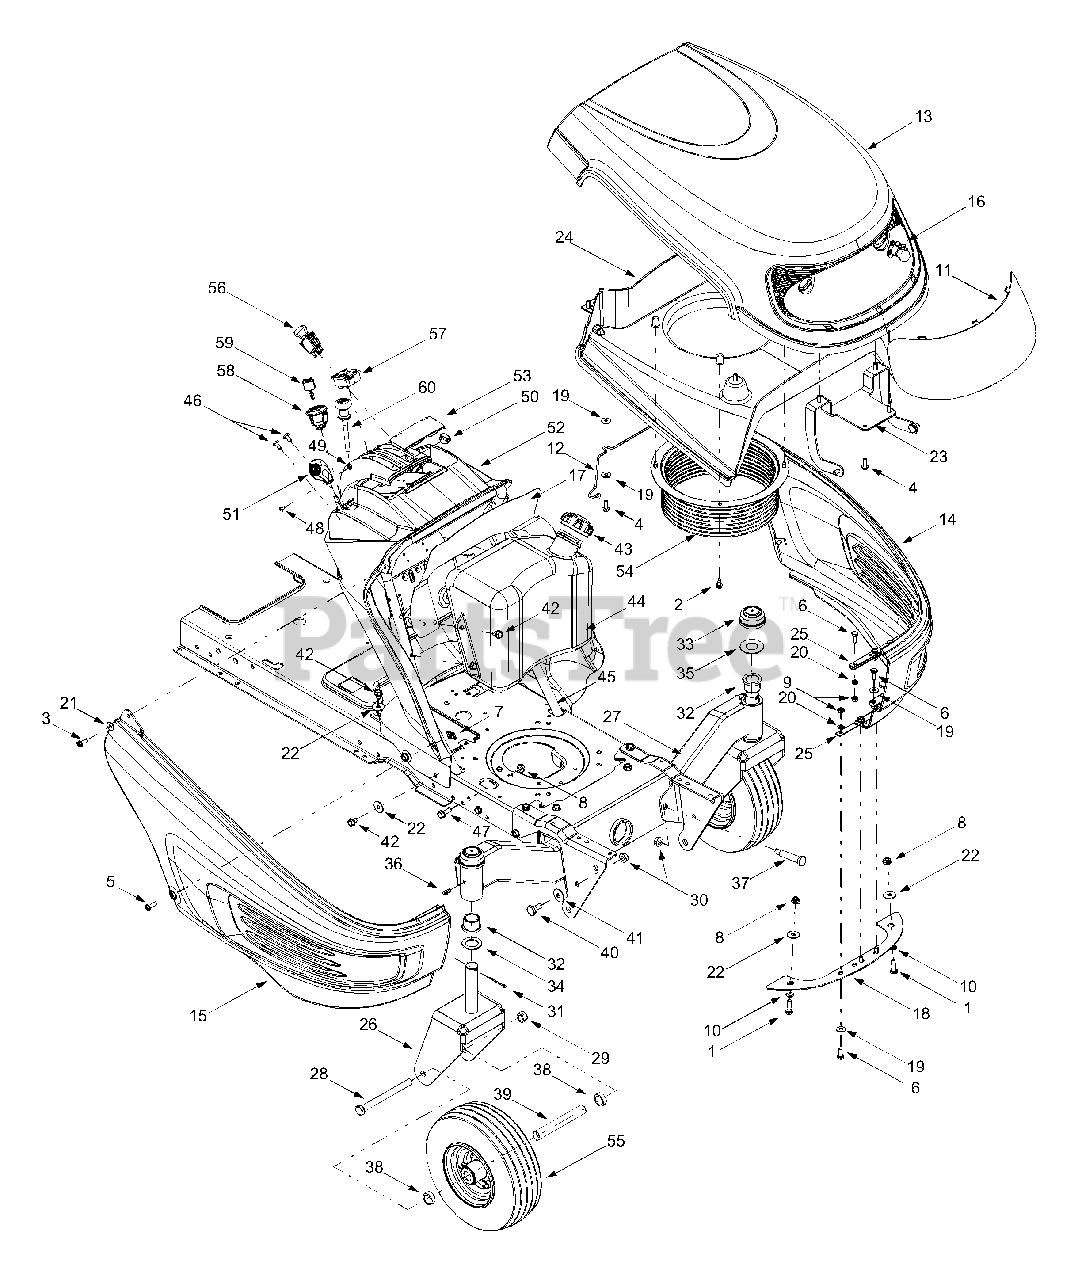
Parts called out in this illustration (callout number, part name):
1	Hex Cap Screw, 5/16-18 x 1.0
2	Self-tapping Screw, 1/4-20 x .5
3	Self-tapping Screw, 1/4-20 x .75
4	Self-tapping Screw, 1/4-15 x .75
5	Pan Phillips Screw, 1/4-20 x .75
6	Hex Cap Screw, 1/4-20 x .75
7	U-type Speed Nut, 1/4-20
8	HEX FLANGE NUT
9	HEX NUT
10	Speed Nut
11	Head Light Lens
12	Hood Latch Rod
13	Hood, 6-style (Gray)
14	LH Side Panel, 6-style (Gray)
15	RH Side Panel, 6-style (Gray)
16	Head Light Assembly
19	Flat Washer, .28 x .74 x .063
20	Lock Washer, 1/4
21	Flat Washer, .283 x .75 x .030
22	Flat Washer, .349 x 1.0 x .063
23	Hood Bracket Assembly
24	Hood Plenum
29	Hex Lock Nut, 1/2-20
30	Flange Lock Nut, 3/8-16
31	Cotter Pin, .125 x 1.5
32	Flange Bearing
33	Plastic Cap
34	Flat Washer, 1.031 x 1.620 x .095
35	Flat Washer, 1.010 x 2.0 x .065
36	Grease Fitting, 1/4-28
37	Shoulder Screw, .50 x 2.23, 3/8-16
38	Spacer, .790 x .347
39	Wheel Spacer
40	SHOULDER SCREW .498 DIA x .340
41	Bell Washer, .39 x 1.13 x .062
42	Self-tapping Screw, 16-18 x .625
43	FUEL CAP (MAX 10% ETHANOL)
44	Fuel Tank, Two-gallon (shown)
47	Hex Head Washer Screw, 5/16-18 x .875
48	Torx Screw, #8-32 x .375
49	Hex Nut, 8-32
50	Cap Plug, .812
51	Throttle Control Lever
52	Dash Panel
53	Dash Cap
54	Intake Bellow (ZTT-1850)
54	Intake Bellow (ZTT-2150)
55	Wheel Assembly, 11 x 4 x 5 (Yellow Rim)
56	Electric PTO Switch
57	Systems Indicator Monitor/Hour Meter
58	Ignition Switch
59	Ignition Key w/ Plastic Cover
60	Choke Control/Cable (ZTT-2150)
